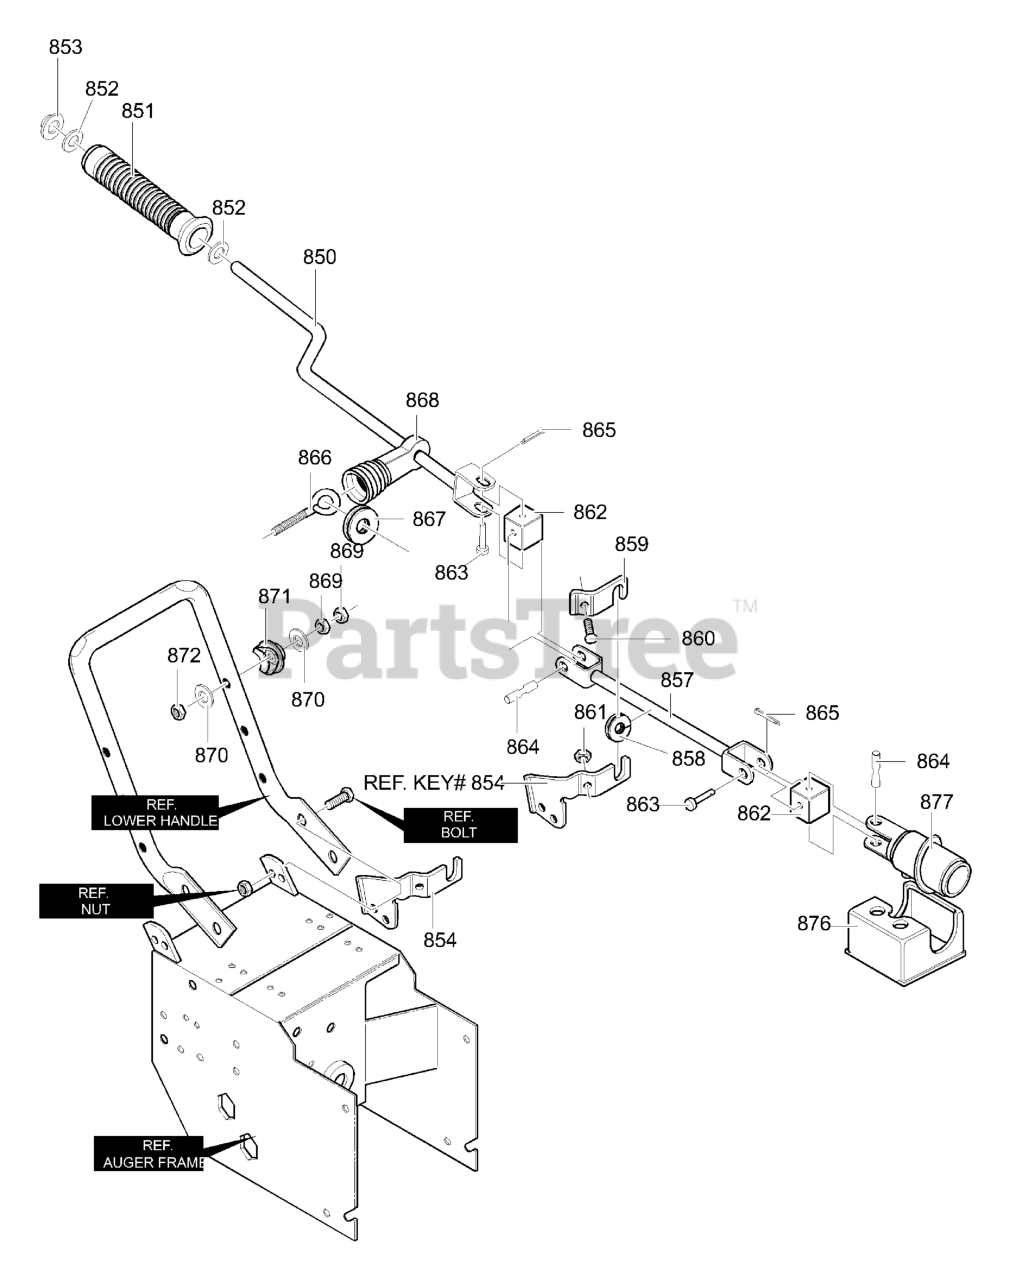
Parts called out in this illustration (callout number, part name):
850	ASSEMBLY, LEFT ROD
851	HANDLE, CRANK
852	WASHER, FLAT
853	RING, RETAINER
854	BRACKET, SUPPORT
857	ASSEMBLY, LEFT ROD
858	GROMMET
859	BRACKET, CHUTE
861	NUT
862	HOUSING, UNIVERSAL
863	PIN, CLEVIS
864	PIN, JOINT
865	PIN, COTTER
866	BOLT, EYE
867	GROMMET, EYE BOLT
868	BOOT, EYEBOLT
870	WASHER, FLAT
871	ADAPTOR, BOOT
872	NUT
876	BRACKET, WORM MOUNT
877	WORM, CHUTE
